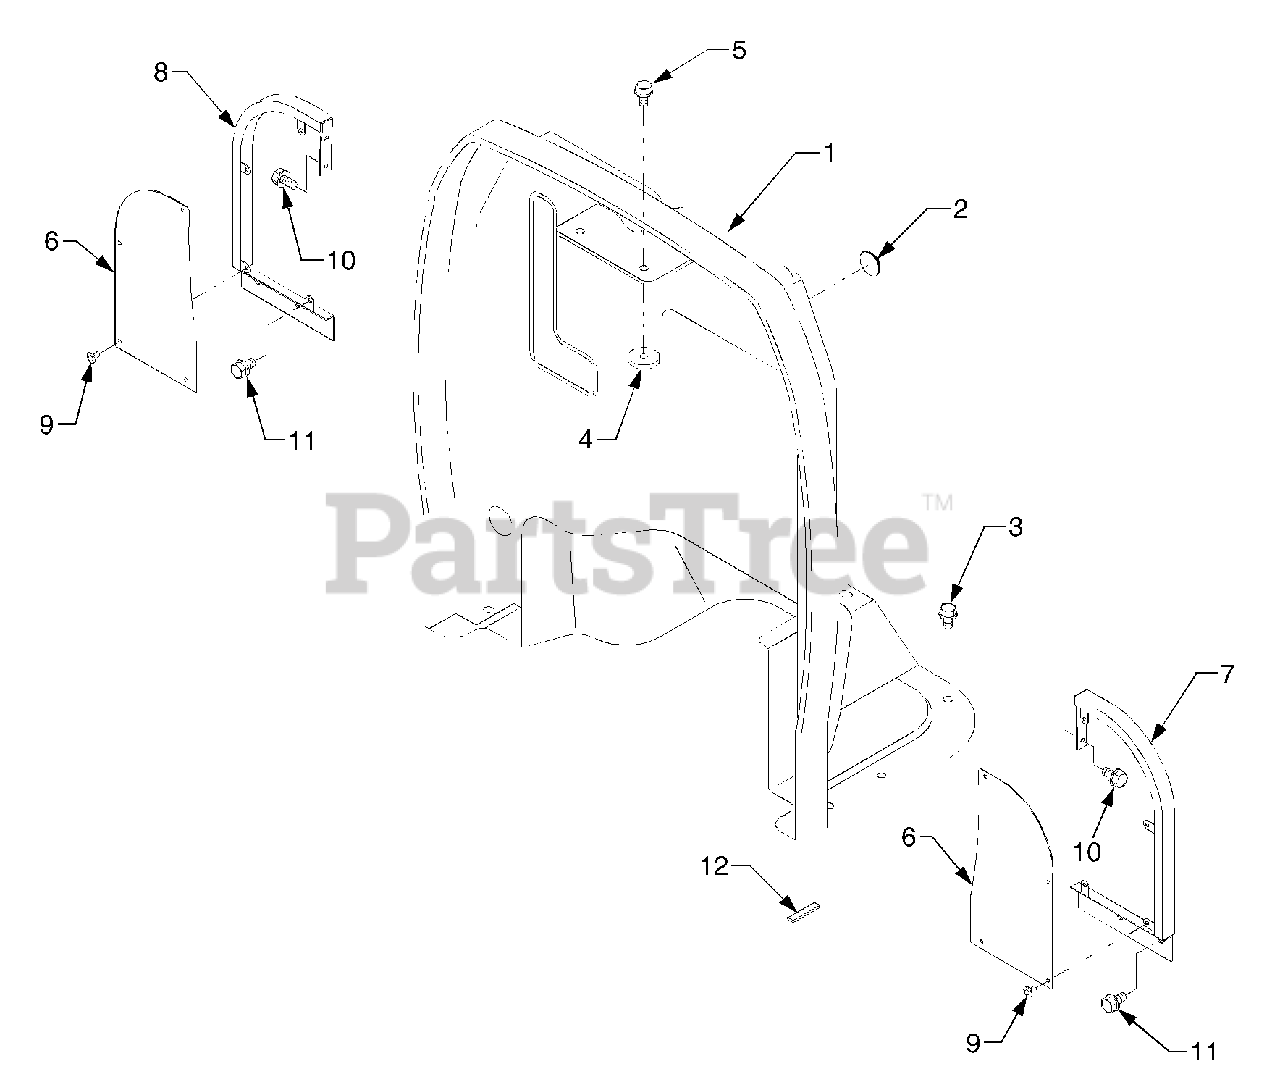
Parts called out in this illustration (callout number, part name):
6	Plate
7	Mudguard Ass'y (LH)
8	Mudguard Ass'y (RH)
12	Rubber, Cushion
